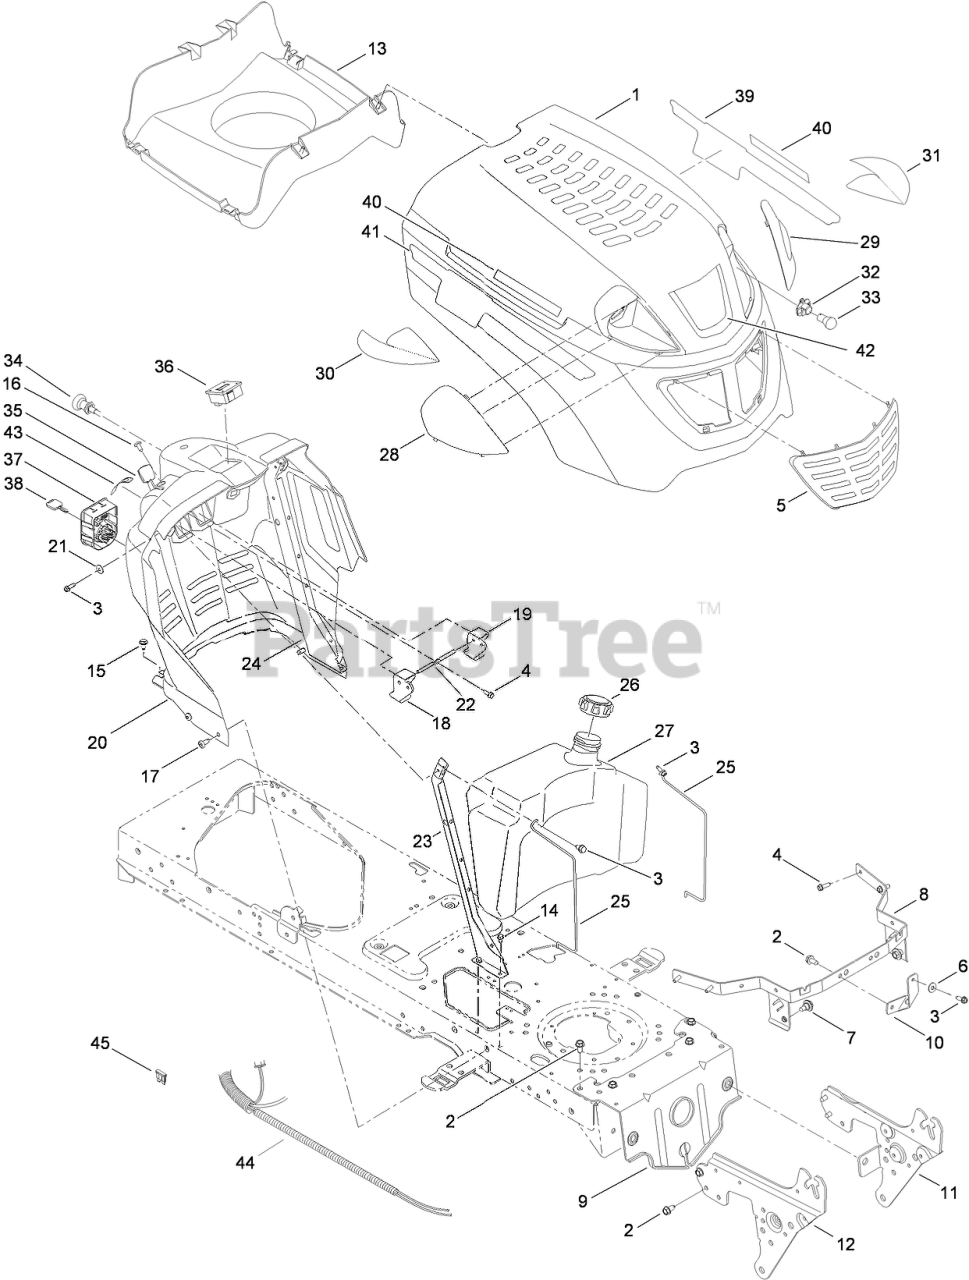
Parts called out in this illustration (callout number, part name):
2	SCREW-TAP
3	SCREW-TAP
4	SCREW-TAP
6	WASHER-FLAT
7	BOLT-SHOULDER, TAP
8	BRACKET-PIVOT, HOOD
9	BRACKET-PIVOT
10	BRACKET-SUPPORT, HOOD
11	BRACKET-PIVOT, SUPPORT (LH)
12	BRACKET-PIVOT, SUPPORT (RH)
13	PLENUM-HOOD
14	SCREW-HWHTF
15	SCREW-TAP
16	SCREW-TAP
17	SCREW-TAP
18	LEVER-CRUISE
19	LEVER-BRAKE
20	DASH-ELECTRIC, PTO
21	WASHER-SPRING
22	ROD-LEVER, BENT
23	SUPPORT-DASH, PLATE (RH)
24	SUPPORT-DASH, PLATE (LH)
25	ROD-SUPPORT
26	CAP-FUEL
27	TANK-FUEL, 3 GAL
28	LENS-RH
29	LENS-LH
30	REFLECTOR-RH
31	REFLECTOR-LH
32	SOCKET-HEADLIGHT
33	LAMP-12V, MINIATURE
34	CABLE CONTROL ASM (W/CHOKE KNOB)
35	CABLE-THROTTLE
36	METER-HOUR
37	MODULE-SWITCH, IGNITION
38	KEY-IGNITION
39	DECAL-HOOD, LEFT SIDE
40	DECAL-SIDE PANEL
41	DECAL-HOOD, RIGHT SIDE
42	DECAL-HOOD
43	DECAL-THROTTLE
44	Harness-Wire
45	FUSE-20 AMP
